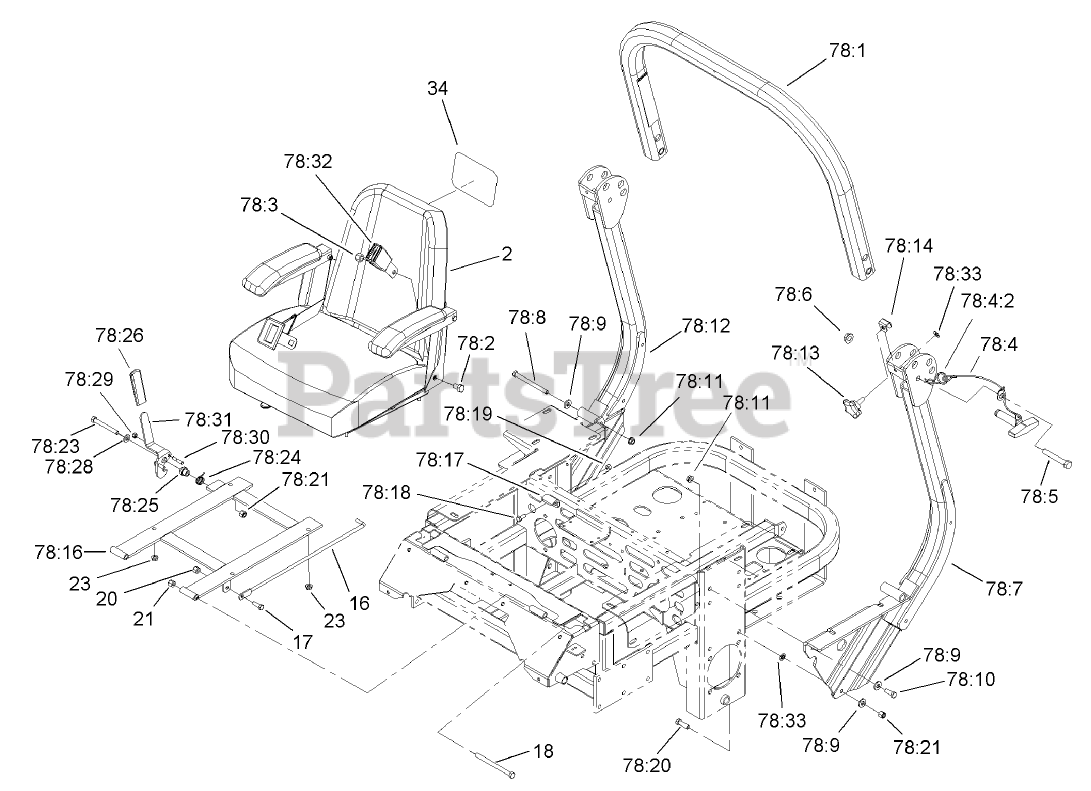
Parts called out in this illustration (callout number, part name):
2	SEAT ASM
16	ROD-HOLDUP, SEAT
17	SCREW-HH
18	SCREW-HH
20	NUT-LOCK, NI
21	NUT-LOCK, NI
23	NUT-HF
34	DECAL
78	ROPS ASM
78:1	Upper Tube ASM W/Decals
78:2	SCREW-HH
78:3	NUT-LOCK
78:4	PIN LATCH ASM
78:4:2	Hairpin
78:5	SCREW-HH
78:6	NUT-HF
78:7	LH Rops ASM
78:8	SCREW-HH
78:9	WASHER-BELLEVILLE
78:10	SCREW-HH
78:11	NUT-HHF, WHIZ
78:12	RH Rops ASM
78:16	SEAT SUPPORT FRAME ASM
78:17	Catch-Latch, Seat
78:18	SCREW-HH
78:19	NUT-LOCK, NI
78:20	SCREW-HH
78:21	NUT-LOCK, NI
78:23	SCREW-HH
78:24	SPRING-TORSION
78:25	BUSHING-LATCH, SEAT
78:26	GRIP-HANDLE
78:28	WASHER-FLAT
78:29	NUT-LOCK, NI
78:32	Belt-Seat
78:33	NUT-PUSH
